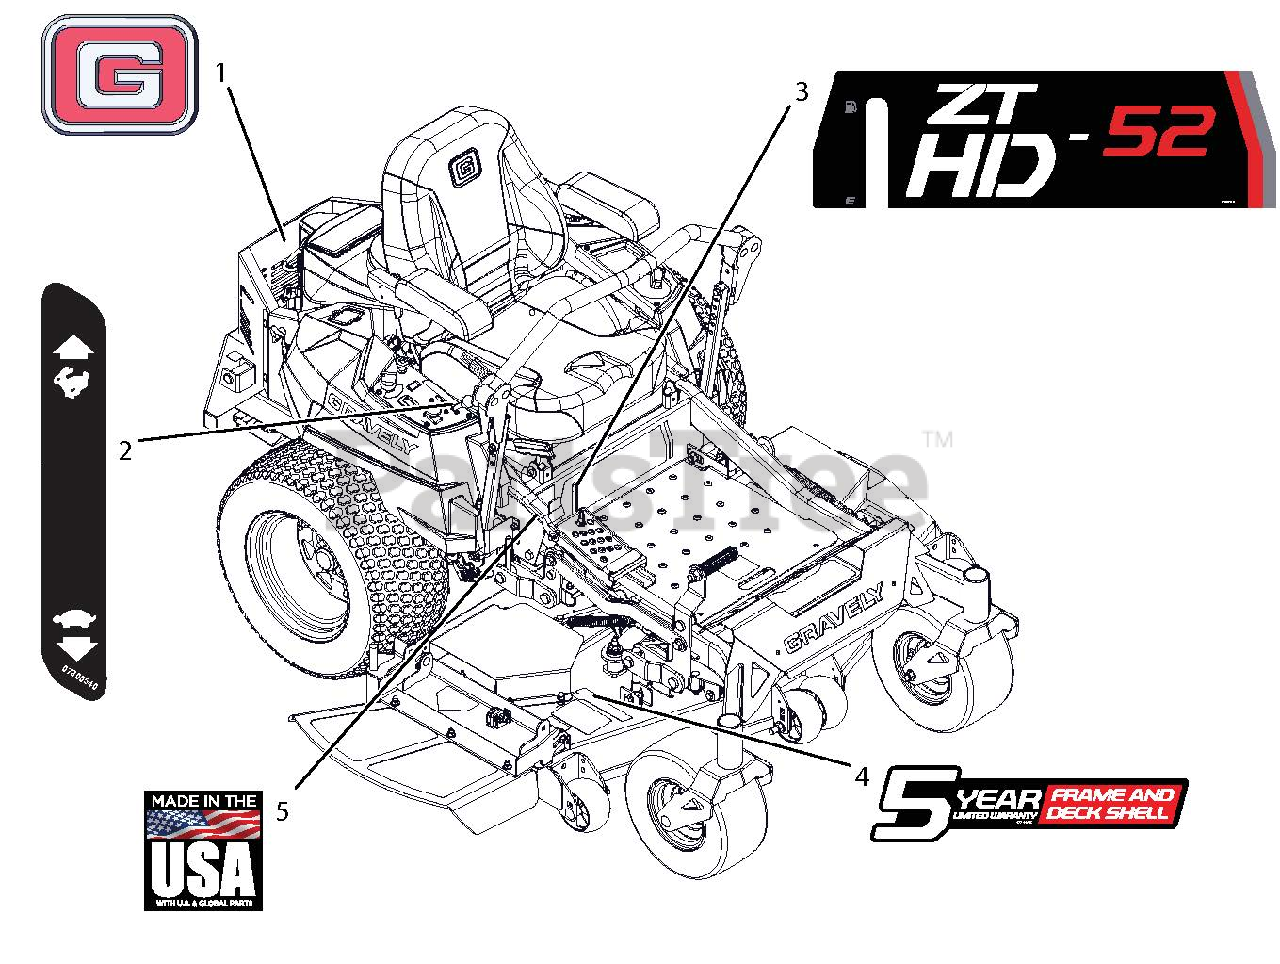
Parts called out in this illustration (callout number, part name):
1	DECAL, GRAVELY BRAND
2	DECAL, DASH DECAL
3	DECAL - 52HD
4	DECAL, DECK 5 YEAR-GRAVELY
5	DECAL, MADE IN USA
